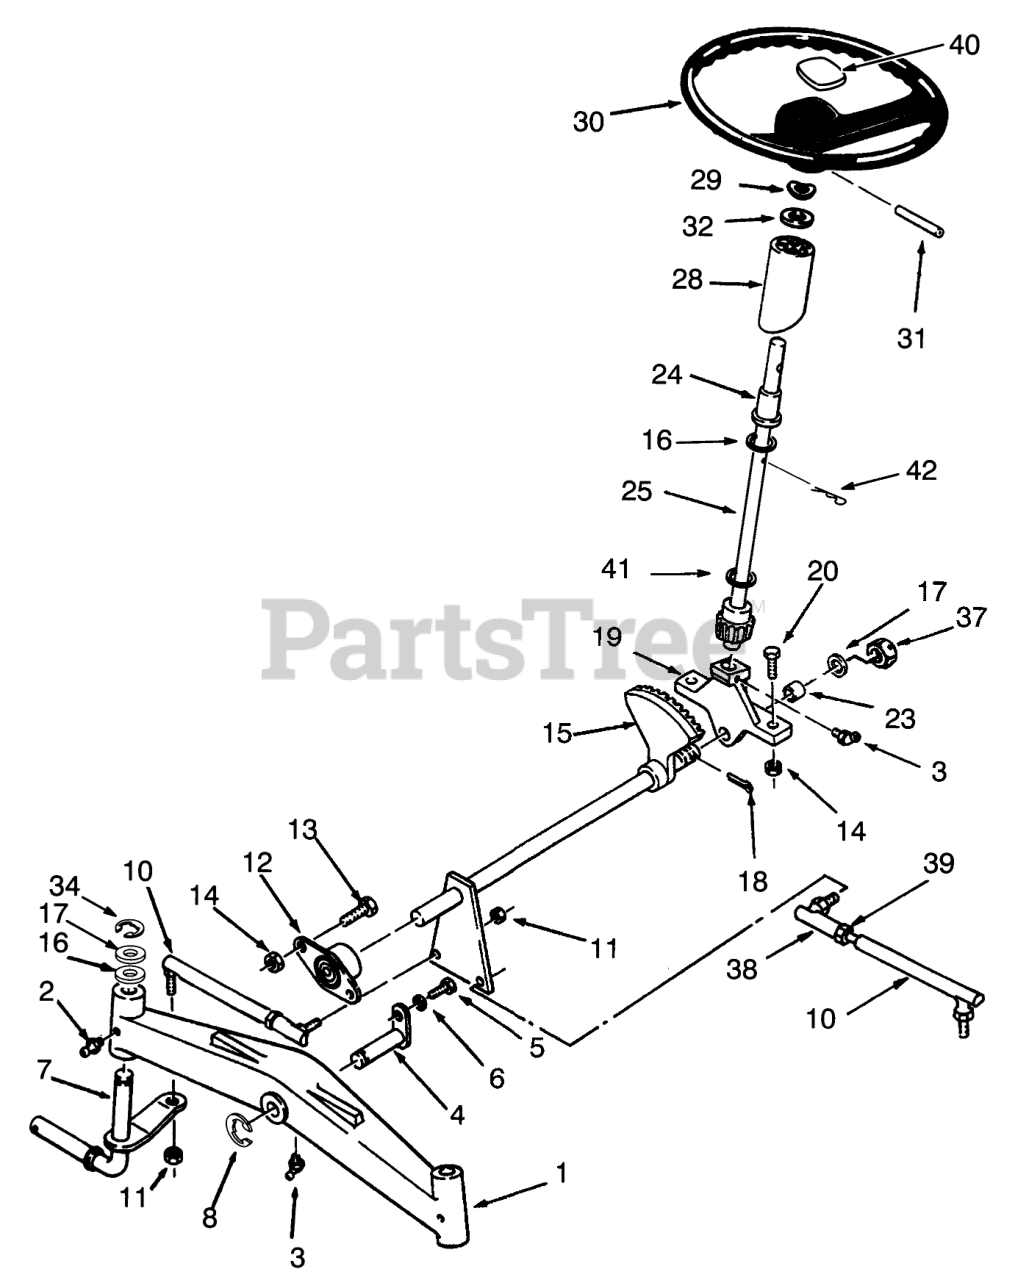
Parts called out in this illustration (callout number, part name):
1	AXLE-FRONT
2	FITTING-GREASE
3	FITTING-GREASE
4	PIN AND PLATE ASM
5	SCREW-HH
6	WASHER-LOCK
7	LH SPINDLE ASM
8	E-RING
10	Tie Rod Assembly (Incl. Ref. #38 & 39)
11	NUT HEX 3/8-24 E.S.
12	BEARING-FLANGED
13	SCREW-HH
14	NUT-LOCK, NI
15	Shaft
16	WASHER-SHIM
17	WASHER
18	PIN-COTTER
19	Support-Steering
20	SCREW-HH
23	BEARING-BRONZE
24	BEARING-FLANGED
25	STEERING SHAFT ASM
28	TUBE-STEERING
29	WASHER-BOWED
30	Steering Wheel (Incl. Ref. #40)
31	PIN-ROLL
32	WASHER-FLAT
34	RING-RETAINING
37	NUT-HEX, SLOTTED
38	BALL-JOINT
39	NUT-6
40	STRG-WHL INSERT TORO
41	O-RING
42	PIN-COTTER
